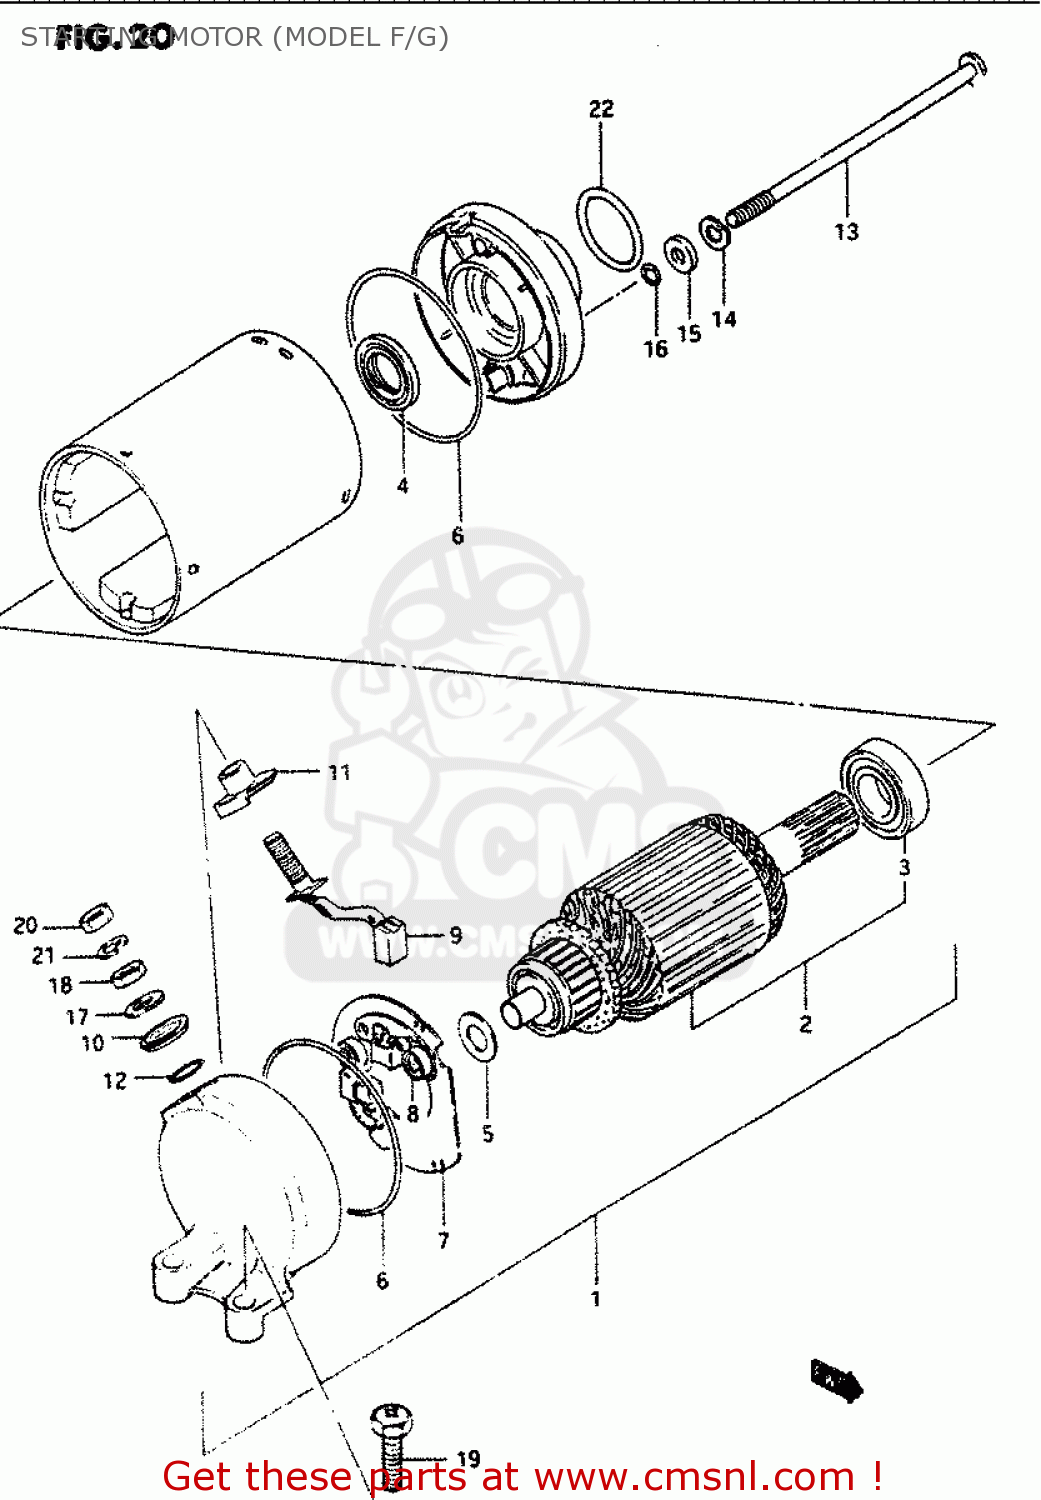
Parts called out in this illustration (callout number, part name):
1	MOTOR ASSEMBLY,STARTING
2	ARMATURE
3	BEARING
4	SEAL,OIL
5	SHIM,ARMATURE
6	O RING
7	HOLDER,BRUSH
8	SPRING
9	BRUSH SUB ASSY,STARTING MOTOR
10	BUSHING
11	BUSH,B
12	O RING
13	BOLT
14	LOCK WASHER
15	WASHER
16	O RING
17	WASHER
18	NUT 6MM
19	SCREW (6X25)
20	NUT
21	WASHER,LOCK
22	O RING(D:3,ID:24.5)
